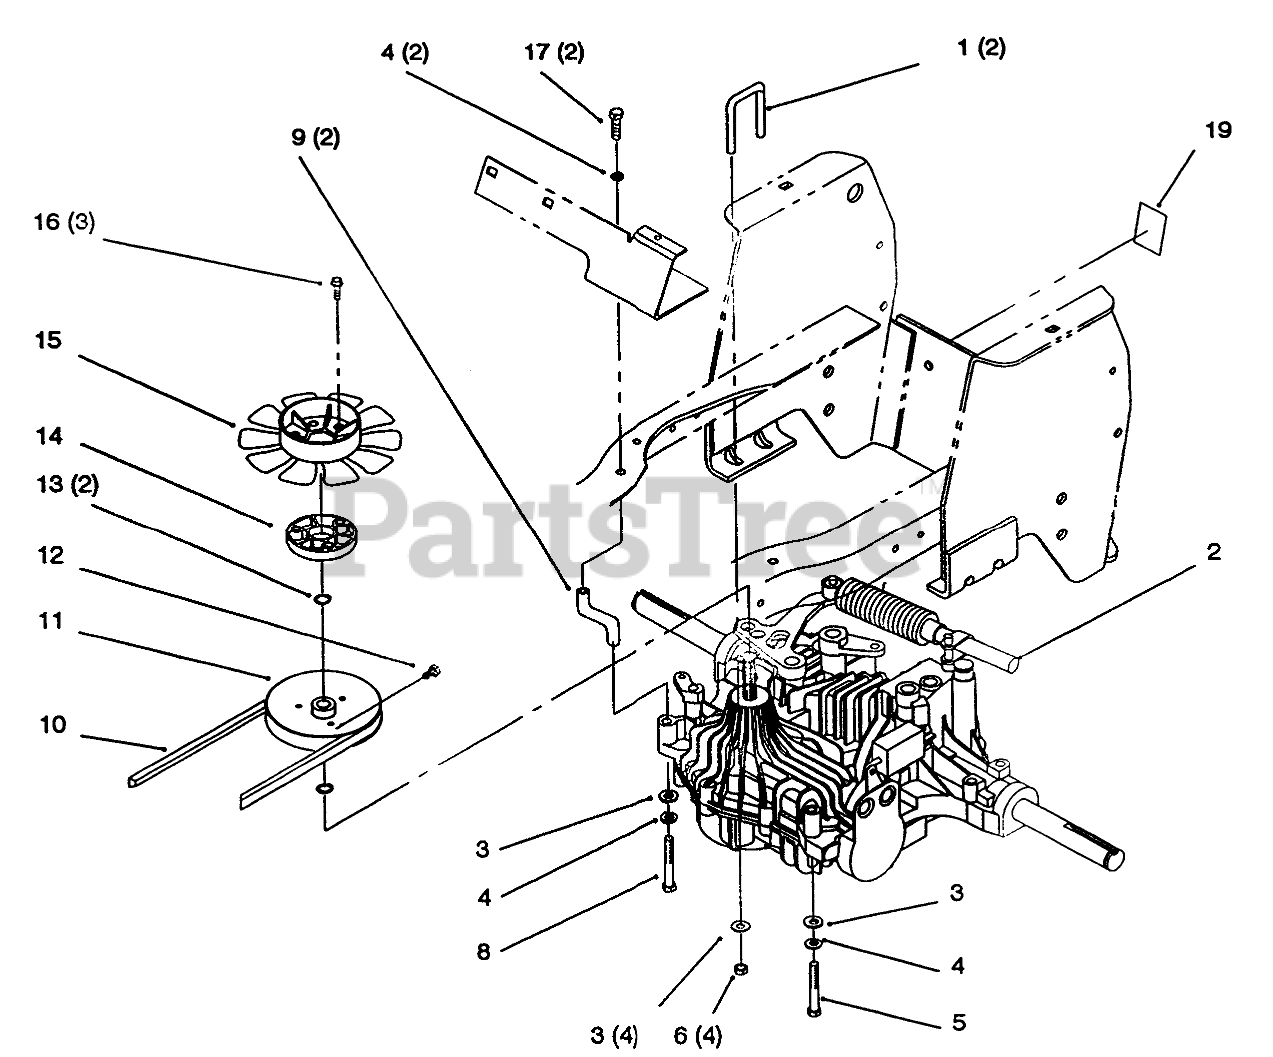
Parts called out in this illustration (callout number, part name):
1	U-Bolt (Only On: 72043,72103,7 72063, 72083)
2	Transaxle-Tuff Torq K61 (Only On: 72043, 72103, 72063,72083)
3	Washer-Flat (Only On: 72103,72063,72083,72043)
4	Washer-Lock (Only On: 72043,72103,72063,72083)
5	Screw HH (Only On: 72043,72103,72063,72083)
6	Nut-Hex Lock (Only On: 72103,72063,72083,72043)
8	Screw-HH (Only On: 72043,72103,72063,72083)
9	Strap-Torque (Only On: 72043,72103,72063,72083)
10	Belt-Hydro (Only On: 72043, 72063, 72083, 72103)
11	Pulley (Only On: 72043,72103,72063,72083)
12	Screw-Set (Only On: 72043,72103,72063,72083)
13	Snap Ring (Only On: 72043, 72103, 72063, 72083)
14	Spacer-Fan (Only On: 72043,72103,72063,72083)
15	Fan (Only On: 72043,72103,72063,72083)
16	Screw-HH (Only On: 72043,72103,72063,72083)
17	Screw-HH (Only On: 72043,72103,72063,72083)
19	Decal-Hydro Valve (Only On: 72043,72083)
19	Decal-Bypass (Only On: 72063,72103)
